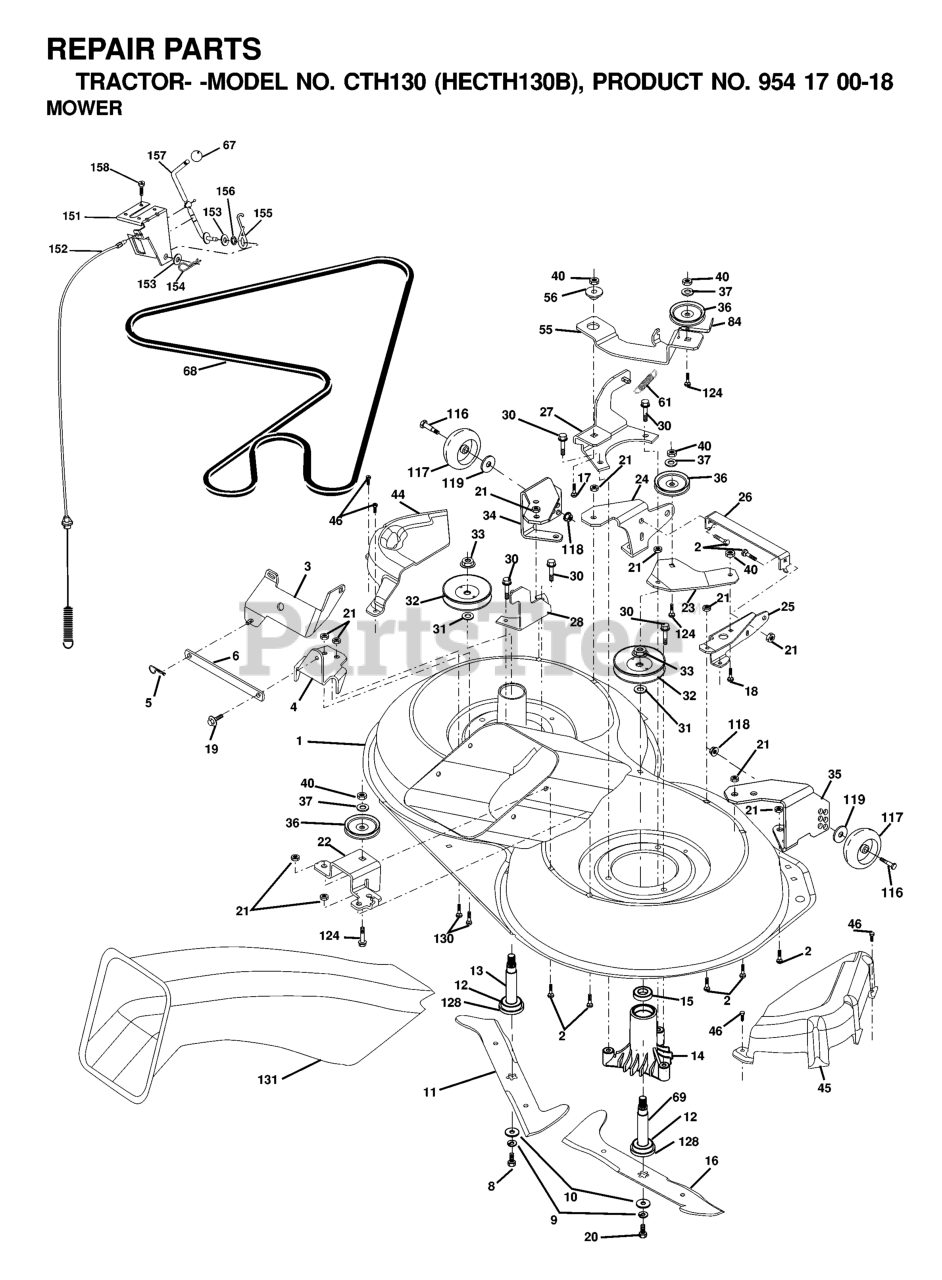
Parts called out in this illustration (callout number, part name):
1	MOWER HOUSING, DECK
2	RP BOLT 5/16-18 X3/4 ZN/YEL GR
5	RETAINER-SPRNG RB
6	BAR.SWAY.92.CRD
8	BLADE BOLT
9	LOCKWASHER
10	WASHER.BLADE
11	BLADE-LH 5PT STAR(CTH130)
12	BEARING.BALL.#6204.(MANDREL)
13	SHAFT ASM VENT
14	HOUSING.MANDREL.VENTED (MACHD)
16	BLADE RH 6PT STAR(CTH130)
17	BOLT.3/8-14X1.25
18	BOLT D
19	BOLT SHD 5/16-18
21	LOCKNUT
26	BRACE.SUPT.SUSP.FRT.CRD
30	SCREW THDROL ROLLING WASHER HD
31	WASHER
32	PULLEY, MANDREL
33	NUT
36	PULLEY.IDLER.4.25
37	WASHER
44	COVER.MANDREL.LH.92.CRD
45	COVER
46	SCREW.1/4-20X5/8
56	SPACER.RETAINER.MOWER
61	SPRING.TENSION.BELT
67	KNOB T (3/8 HOLE)
69	SHAFT.ASM.W/LWR.BRG.RH.THREAD
84	KEEPER, BELT IDLER
116	BOLT, SHOULDER
117	WHEEL GAGE DONUT
118	LOCKNUT
119	WASHER.5/16.FLAT.STE.STD.
124	BOLT.3/8-16X1.50
128	WASHER FELT
130	BOLT.CARR.SQNK.5/16-18UNC.X3/4
131	CHUTE BAGGER
151	BRACKET.CLUTCH.CABLE
152	Cable Clutch CRD Service
153	WASHER FLAT 3/8"
154	SPRING RETAINER
155	SPRING RETENTION LEVER
156	SPACER.CLUTCH.CABLE
157	ROD CLUTCH CABLE 3/8"
158	SCREW LT
